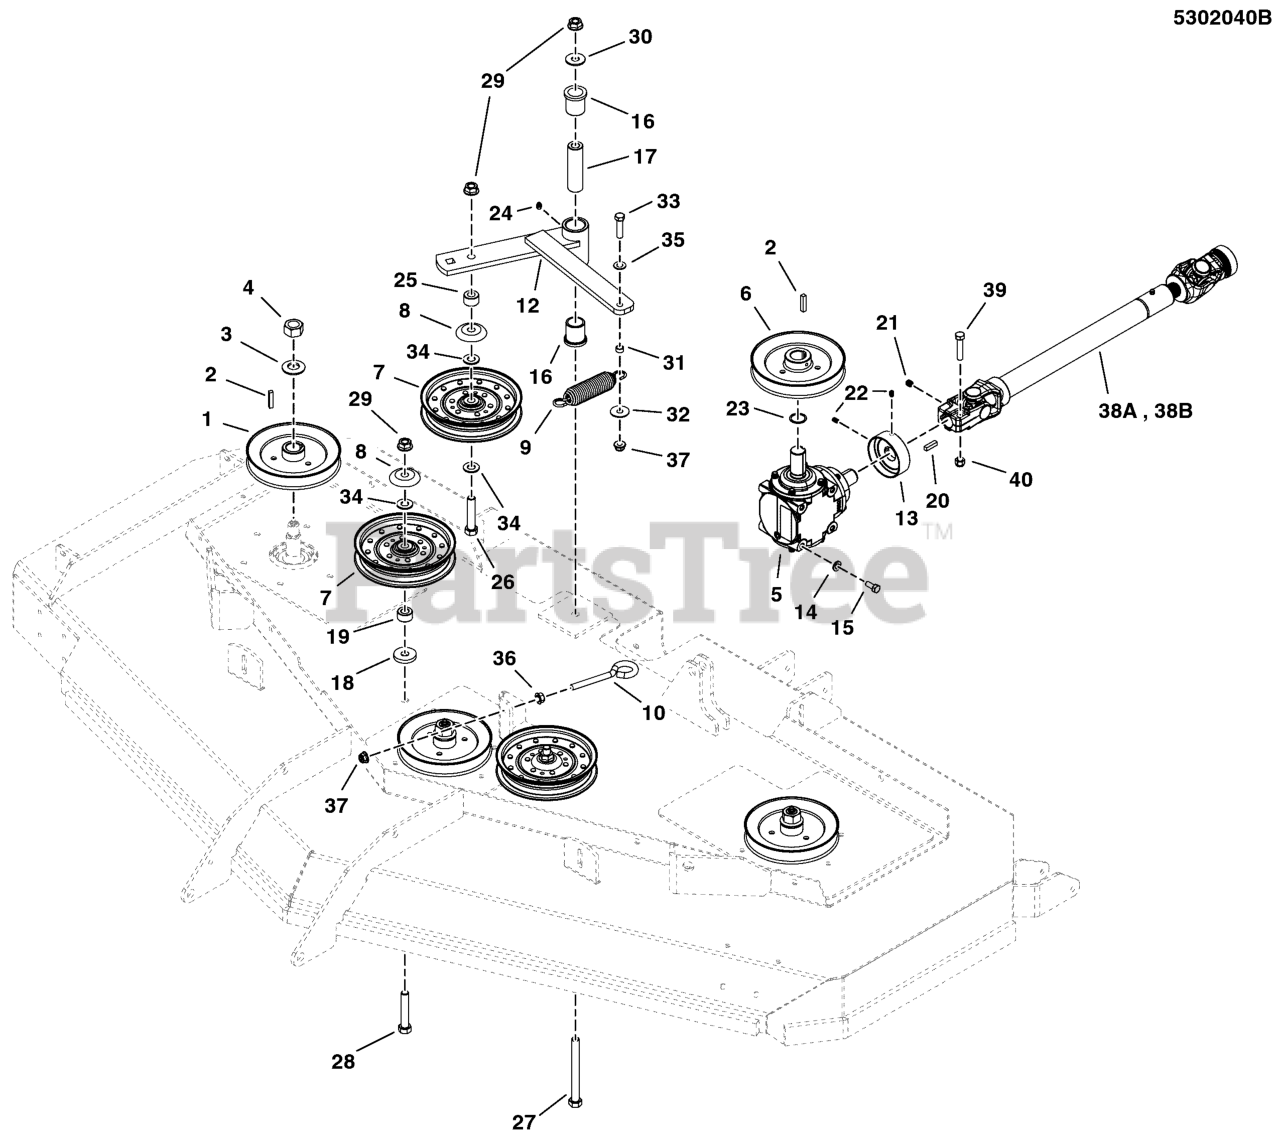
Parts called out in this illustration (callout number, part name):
1	PULLEY, 6.122 OD X .98 BORE
2	KEY, 1/4" SQ. X 1-1/4
3	WASHER, 3/4 BELLEVILLE CL/ZC
4	NUT, 3/4-16 Hex
5	GEAR BOX, RIGHT ANGLE
6	PULLEY, 6.25" SPLIT STEEL W/ 1" ID
8	SHIELD, PULLEY BEARING, CZ
9	SPRING-EXT, 1.25 ODX5.70LGX.142WR, BLK
10	EYE BOLT, 3/8-16 X 5, 2.88THRD, 1EYE, CZ
12	WELD., IDLER ARM, S800X-72 - RED
13	GUARD, TRASH, S800X
14	WASHER, 5/16 LOCK CZ
15	BOLT, 5/16-18 X 3/4 GD5
16	BUSHING, FLANGE
17	SPACER, .52 x 1.00 x 3.50
18	WASHER, .53 X 1.50 X .25
19	SPACER, .52 X 1.00 X .56, PM, CZ
20	KEY, 1/4 SQ X 1
21	SET SCREW, 3/8-16 X 3/8
22	SOC SET SCREW, 1/4-20X3/8, DRI-LOC PATCH
23	SNAP RING, EXTERNAL, 1 SHAFT
24	GREASE FITTING, 1/4-28 Straight
25	SPACER, .52 X 1.00 X .63, YZ
26	BOLT, 1/2-13 X 2-1/2" GD5 CZ
27	BOLT, 1/2-13 X 5" GD5 YZ
28	BOLT, 1/2-13 X 2-3/4 GD5 CZ
29	NUT, Hex Flange, Nylock, 1/2-13
30	WASHER, 1/2" USSZ
31	SPACER, .38 X .50 X .27, CZ
32	WASHER, 3/8" Fender
33	BOLT, 3/8-16 X 1-1/2" GD5 CZ
34	WASHER, 1/2 SAE
35	WASHER, 3/8 SAE
36	NUT, 3/8-16 Hex Large Serrated Flange
37	NUT, 3/8 - 16 HEX NYLOCK FLANGE
38A	SHAFT, TELESCOPING DRIVE, OUT-FRONT
38B	DRIVE SHAFT SEALED S800 GAS - NET
38B	DRIVE SHAFT, S800XY
39	BOLT, 3/8-16 X 1-3/4" GD5 CZ
40	NUT, 3/8-16 HEX NYLON LOCK
